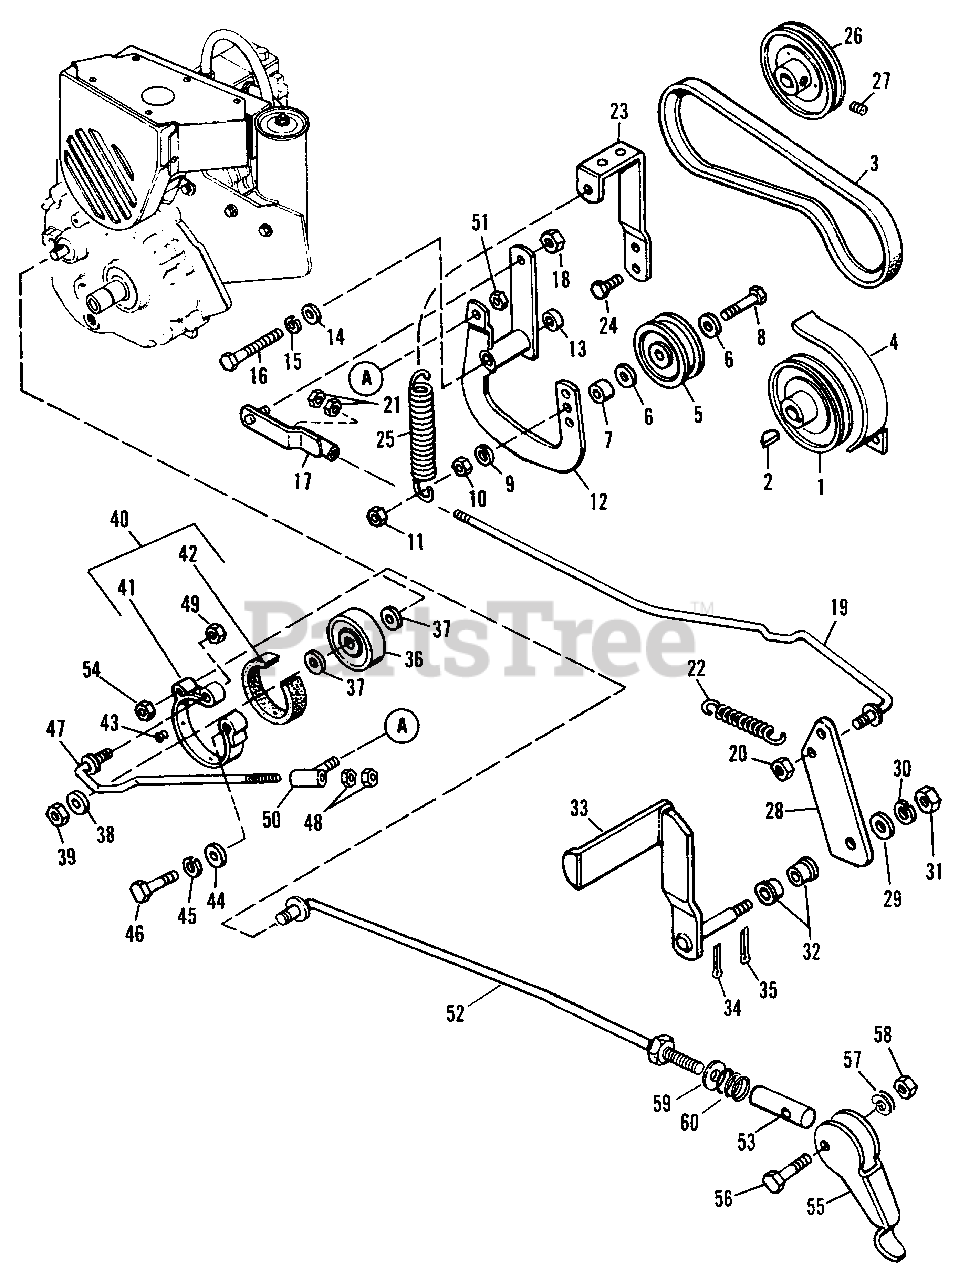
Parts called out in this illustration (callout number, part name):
1	Driver Pulley
2	Woodruff Key, 3/16" x 3/4"
3	BELT, A-Sect, 47.30
4	Belt Guard Assy.
5	Idler Pulley
6	Plain Washer, 3/8"
8	Hex Cap Screw 3/8"-16 x 2-1/4"
9	Lock Washer, 3/8"
10	Full Hex Nut, 3/8"-16
11	Jam Hex Lock Nut, 3/8"-16
12	Idler Lever Assy.
14	Plain Washer, 3/8"
15	Lock Washer, 3/8"
16	Hex Cap Screw, 7/16"-14 x 3-3/4"
17	Rod Guide Assembly
18	Full Hex Lock Nut, 5/16" 18
19	Clutch Rod Assy.
20	Hex Nut, Full, Lock, 5/16" 18
21	Full Hex Nut, 5/16"-18
22	Front Tension Spring
23	Spring Bracket, 1/4" x 1 x 11-1/4"
24	Hex Hd. Cap Screw, 3/8" x 3/4"
25	Idler Pulley Spring
26	Driven Pulley
27	Cup Pt. Socket Hd. Set Screw, 5/16"-18 x 5/16"
28	Foot Pedal Arm, 1/4" x 1-3/4" x 5-7/8"
29	Plain Washer, 3/8"
30	Lock Washer, 3/8"
31	Full Hex Nut, 3/8"-16
33	Foot Pedal Assy.
34	Cotter Pin, 3/32" x 3/4"
35	Cotter Pin, 1/8" x 3/4"
38	Plain Washer, 3/8"
39	Lock Nut, 7/16"-14
40	Brake Band & Lining Assy.
42	Brake Lining
43	Rivet No. 7 x 1/4"
44	Plain Washer, 5/16"
45	Lock Washer, 3/8"
46	Hex Cap Screw, 3/8"-16 x 1-3/4"
47	Brake Rod Assy.
48	Full Hex. Nut, 3/8"-16
49	Full Hex Lock Nut, 3/8"-16
50	Rod Guide Assy.
51	Full Hex Lock Nut, 5/16"-18 N.C.
52	Parking Brake Rod Assy.
54	Full Hex Nut, 5/16"-18
55	Parking Brake Lever
56	Hex Cap Screw, 1/4"-20 x 1-1/4" Grade 8
57	Double Lock Washer, 1/4"
58	Hex Nut, Full, Lock 1/4"-20
59	Plain Washer, 1/2"
